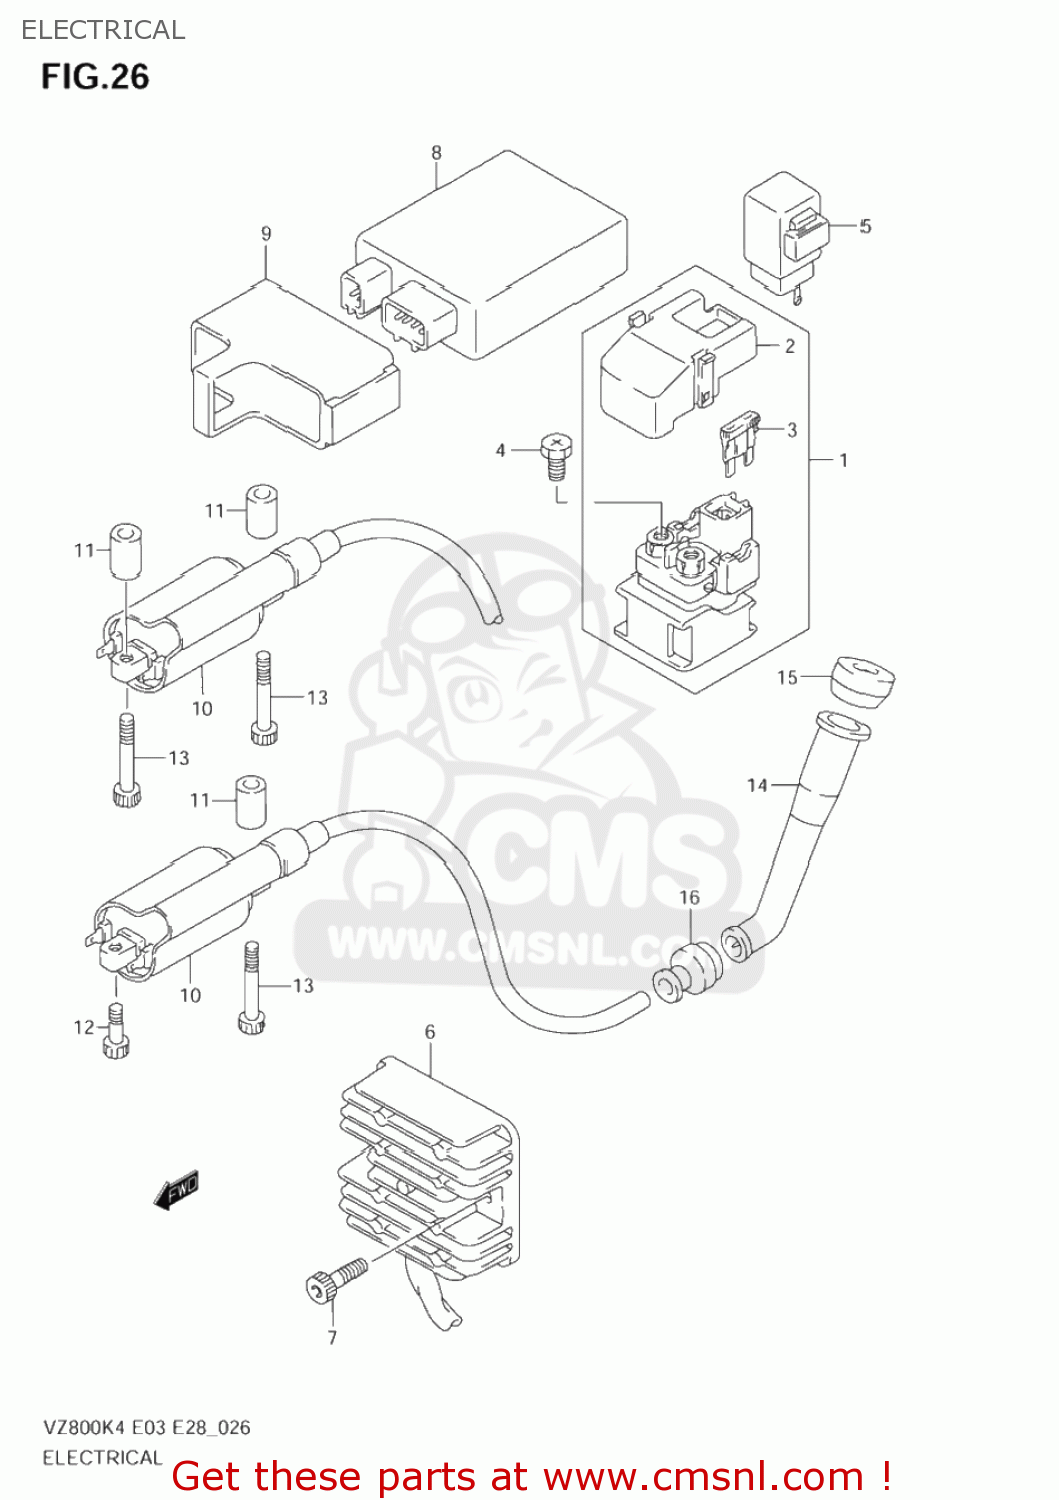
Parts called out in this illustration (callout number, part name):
1	RELAY ASSY,STARTING MOTOR
2	COVER
3	FUSE(30A)
4	SCREW(6X8)
5	CONTROL UNIT,STG MOT RLY
6	RECTIFIER ASSY
7	BOLT,OIL FILLE
8	IGNITOR ASSY
9	CUSHION,IGNITOR
10	COIL ASSY,IGNITION
11	SPACER(6.2X12X16)
12	BOLT
13	BOLT
14	CAP,SPARK PLUG
15	SEAL,SPARK PLUG
16	SEAL,HIGH TENSION CORD
